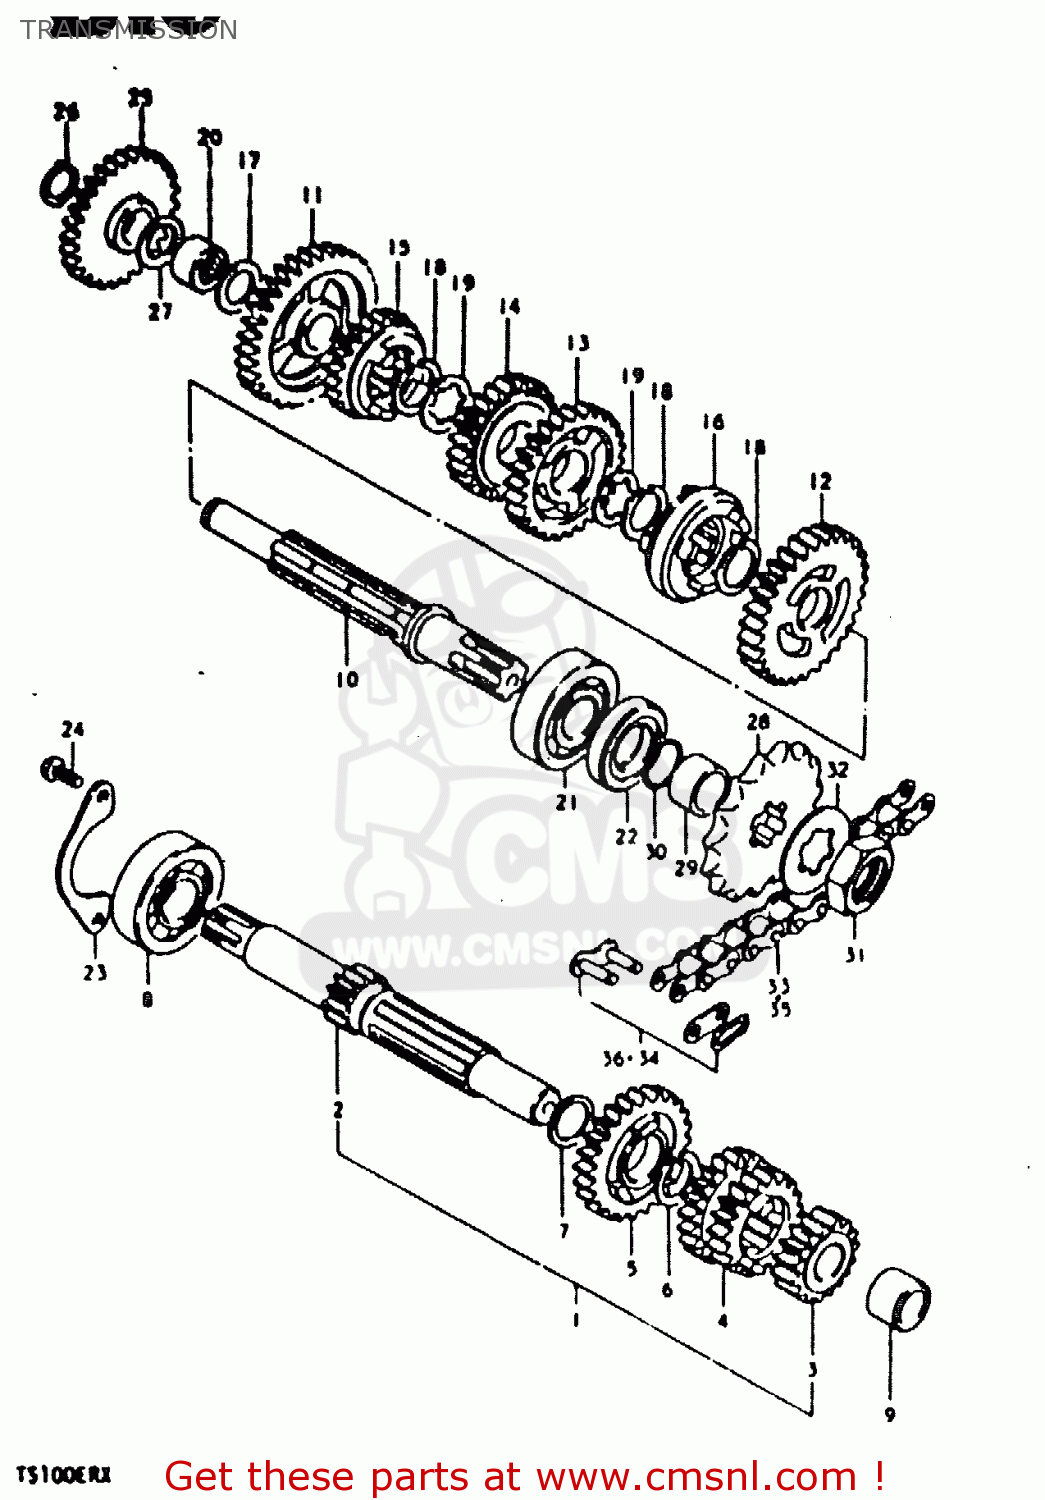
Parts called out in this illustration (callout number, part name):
1	SHAFT ASSEMBLY,COUNTER
2	SHAFT,COUNTER
3	GEAR,SECOND DRIVE
4	GEAR,THIRD/FOURTH DRIVE
5	GEAR,FIFTH DRIVE
6	CIRCLIP
7	WASHER
8	Bearing
9	BUSH(15X22X15)
10	SHAFT,GEAR SHIFT
11	GEAR,1ST DRIVEN
12	GEAR,SECOND DRIVEN
13	GEAR,THIRD DRIVEN
14	GEAR,FOURTH DRIVEN
15	GEAR,FIFTH DRIVEN
16	WHEEL,SECOND DRIVEN GEAR
17	WASHER,THRUST
18	CIRCLIP
19	WASHER,LOCK
20	BEARING(15X22X12)
21	Bearing
22	SEAL,OIL(25X40X7)
23	RETAINER,CNTR SHAFT BEARING
24	SCREW 6X12
25	GEAR,KICK STARTER IDLE
26	CIRCLIP,15MM
27	WASHER,THRUST
28	SPROCKET,ENGINE
29	SPACER(20X25X12.5)
30	O RING(D:1,ID:19.5)
31	NUT
32	WASHER,LOCK
33	CHAIN ASSEMBLY,DRIVE
34	JOINT ASSEMBLY,CHAIN
35	CHAIN ASSEMBLY,DRIVE
36	JOINT ASSEMBLY,CHAIN
